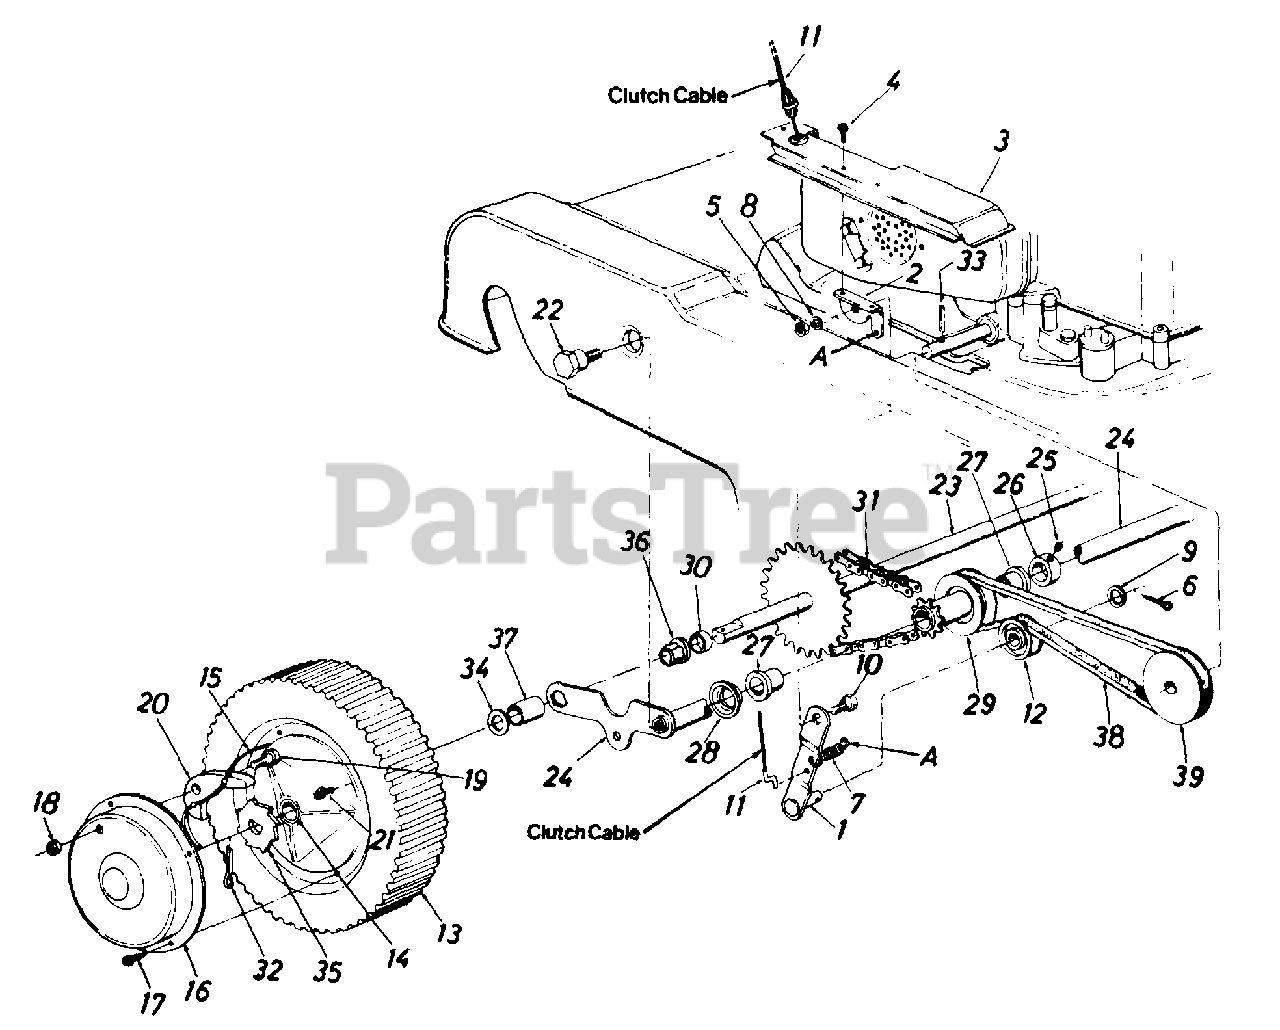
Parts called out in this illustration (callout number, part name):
1	Idler Brkt. Ass'y.
2	Idler Mounting Brkt.
3	Belt Guard
4	Hex Wash. Hd. AB-Tap Scr. 1/4" x .62" Lg.
5	Hex Nut 5/16-18 Thd.
6	Cotter Pin 1/8" Dia. x 1.00" Lg.
7	Extension Spring .33" O.D. x 1.12" Lg.
8	L-Wash. 5/16" I.D.
9	Fl-Wash. .531" I.D. x .930" O.D. x .050
10	Shld. Bolt .375" Dia. x 1.89
11	Clutch Cable - 59"
12	Flat Idler 1.62" Dia.
13	Wheel Ass'y. Comp. (Rear)
14	Flange Brg. 1/2" I.D. (Rear)
15	Spring - Nylon
16	Rear Hub Cap
17	Pan Hd. Tap Scr. #12 x .50" Lg.
18	Hex Ins. L-Nut 1/4-20 Thd.
19	Shld. Bolt .342" Dia. x .268
20	Pawl
21	Hex Wash. Hd. Tap Scr. #8 x .50" Lg.
22	Shld. Bolt .625" Dia. x .425" Lg.
23	Rear Shaft Ass'y.
24	Rear Axle Ass'y.
25	Set Scr. 5/16-18 x .25" Lg. Cup Point
26	Collar 5/8" I.D.
27	Flange Brg. .634" I.D. Plastic
29	Pulley w/9 Tooth Sprocket Ass'y.
30	Spacer .53" I.D. x .75" O.D. x .38" Lg.
31	#48 Chain 1/2" Pitch x 32 Links
32	Cotter Pin 1/8" Dia. x 1.00." Lg.
33	Spring Pin Spir. 3/16" Dia. x 1.50" Lg.
34	Fl-Wash. .531" I.D. x .930" O.D. x .050
35	Ratchet - Rear Wheel
36	Hex Flange Brg. .506" I.D.
37	Spacer .756" I.D. x .89" O.D. x .960" Lg.
38	"V"-Belt 1/2" x 24" Lg.
39	1/2" "V" Pulley .50" I.D. x 2.52" O.D.
